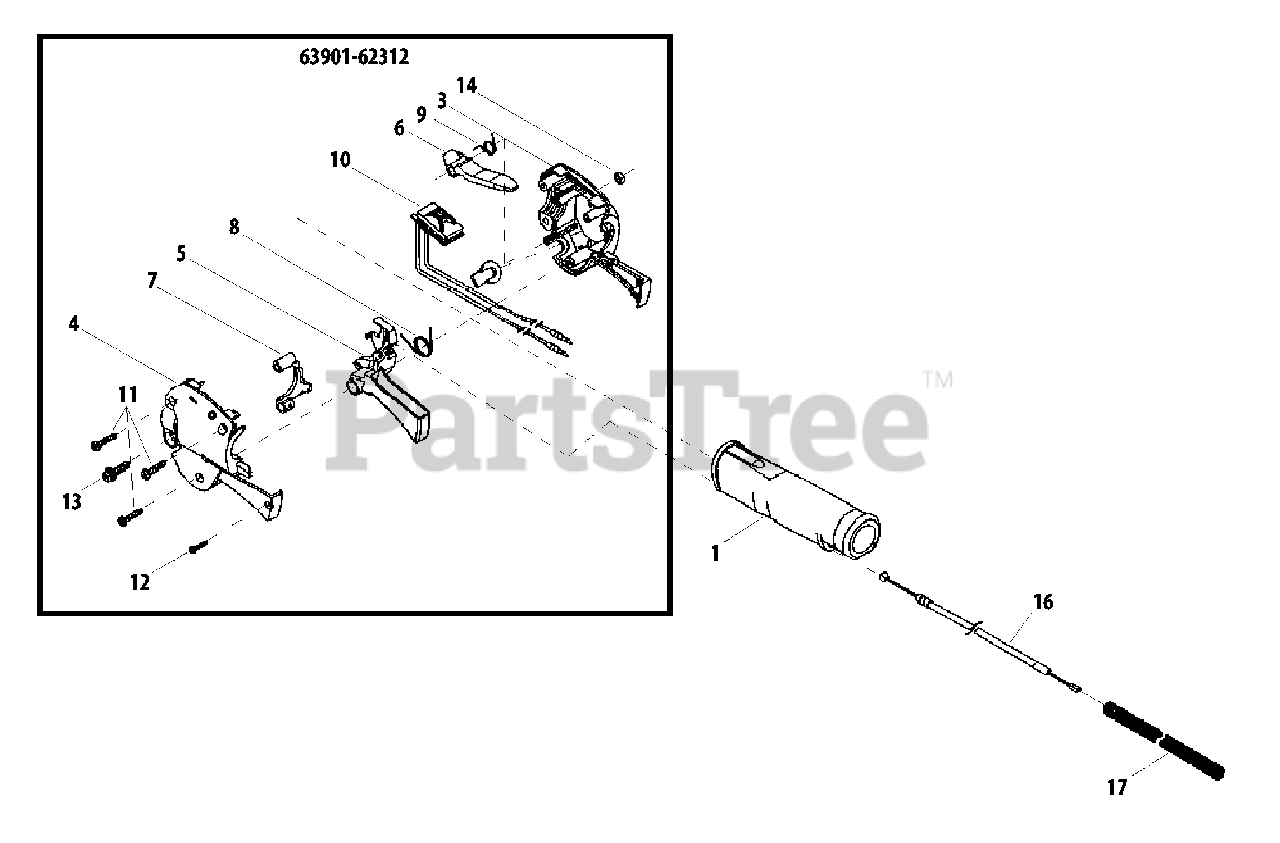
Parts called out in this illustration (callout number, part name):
1	GRIP
3	HANDLE, CONTROL - RIGHT
4	HANDLE, CONTROL - LEFT
5	LEVER
6	LEVER, LOCK
7	HOLDER
8	SPRING
9	SPRING
10	SWITCH, IGNITION
11	SCREW - 4X20 -- TAPPING
12	SCREW - 3X14 -- TAPPING
13	SCREW - 5X20
14	NUT - 5
16	CABLE, THROTTLE
17	TUBE
63901-62312	THROTTLE LEVER ASSY
